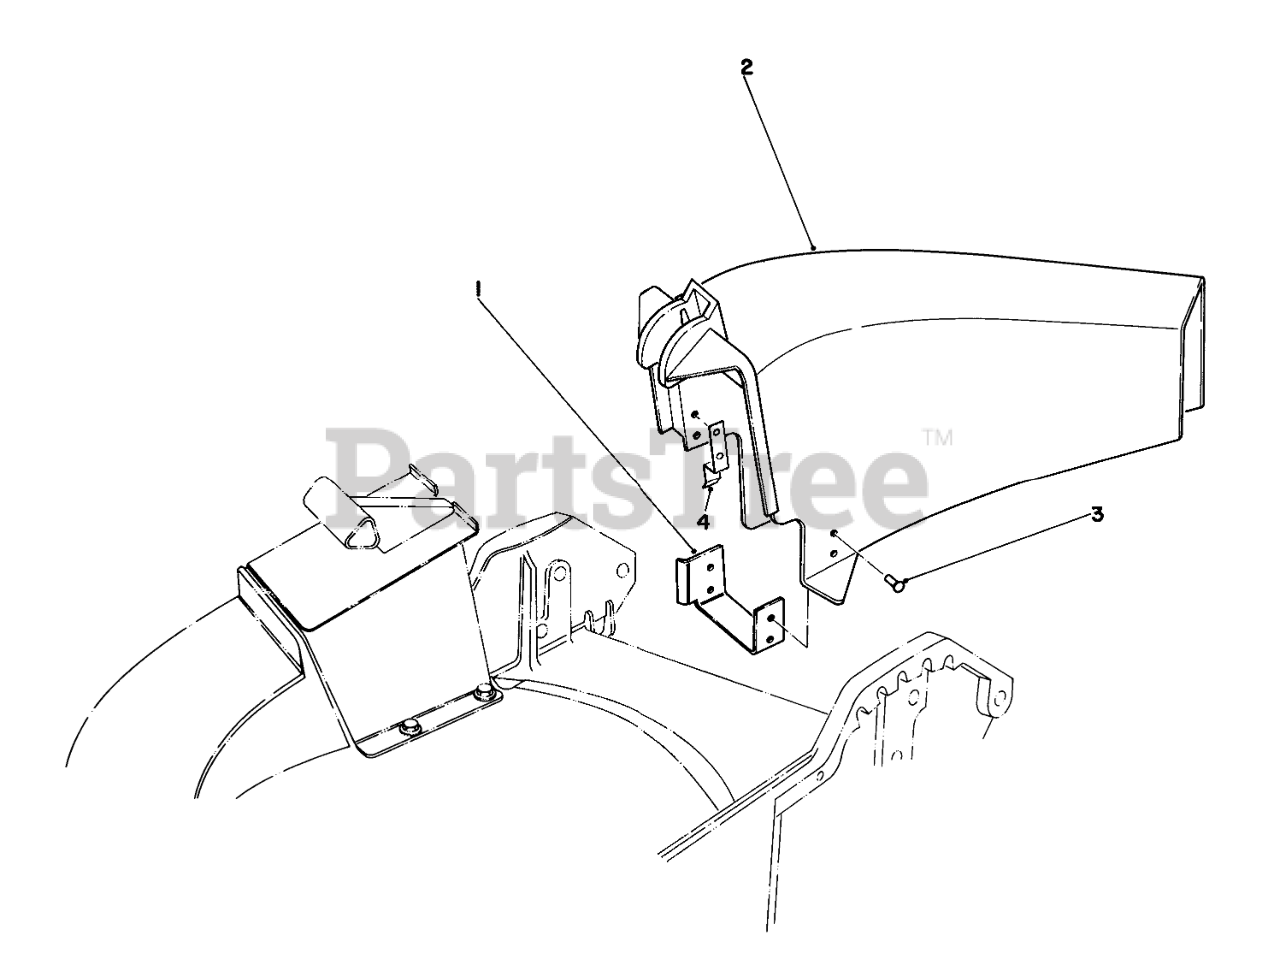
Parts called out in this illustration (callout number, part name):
1	CHUTE BRACKET
2	Chute Discharae
3	RIVET
4	CHUTE TAB
